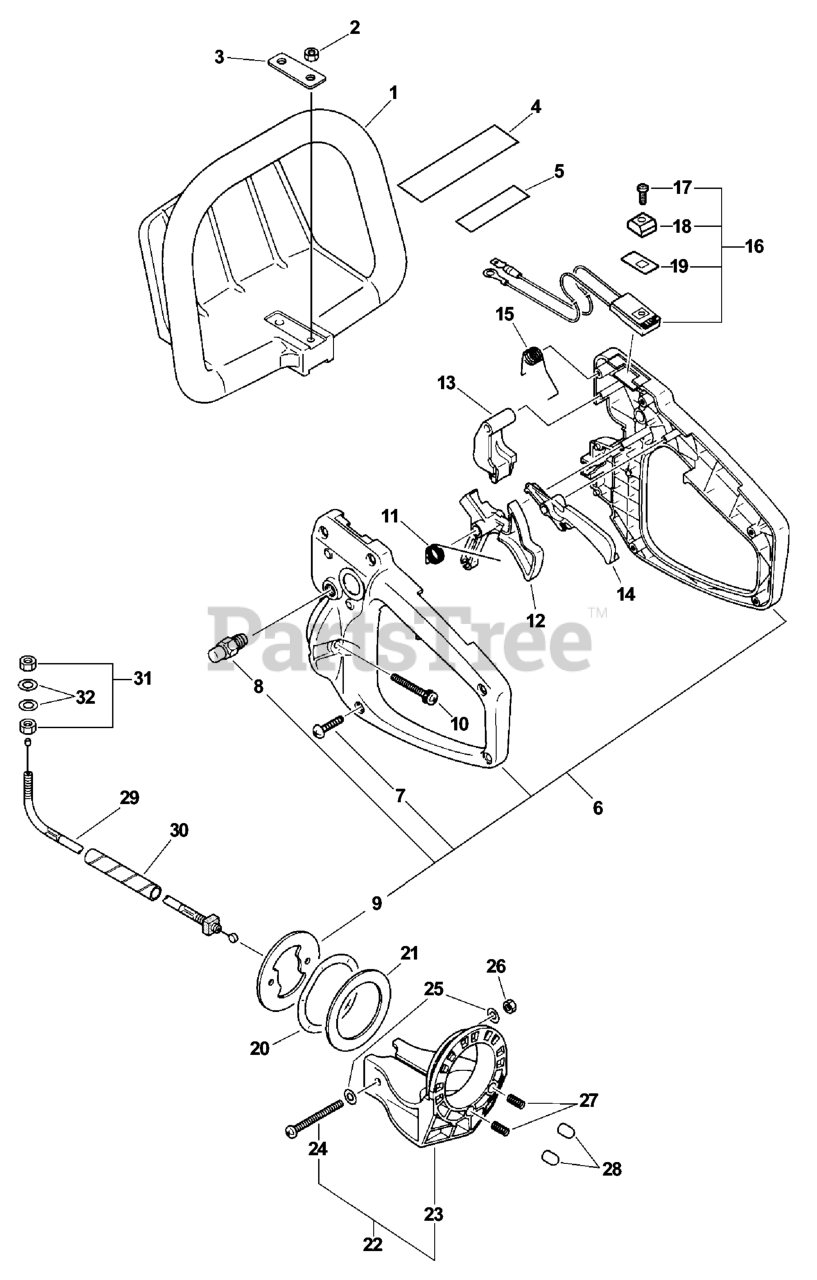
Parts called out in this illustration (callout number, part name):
1	HANDLE, SUPPORT
2	NUT, LOCK M5
3	PLATE, EYE
4	LABEL - CAUTION
5	LABEL - CAUTION
6	HANDLE ASSY, REAR
7	SCREW 4x16
8	LOCK, THROTTLE
9	BRACKET, HANDLE
10	SCREW 5x30
12	TRIGGER, THROTTLE
14	LOCKOUT, THROTTLE
15	SPRING, TORSION
16	SWITCH, ON-OFF
17	KNOB, SWITCH - ORANGE
18	SCREW 3x10
19	LABEL - SWITCH
20	WASHER
22	BRACKET, HANDLE
23	BRACKET, HANDLE
24	SCREW 5x47
25	WASHER, FLAT 5.5x10x0.8
26	NUT, LOCK M5
28	PIN, CLEVIS
29	CABLE, THROTTLE
30	PIPE
31	NUT M6
32	WASHER 6.5x11.5x0.8
